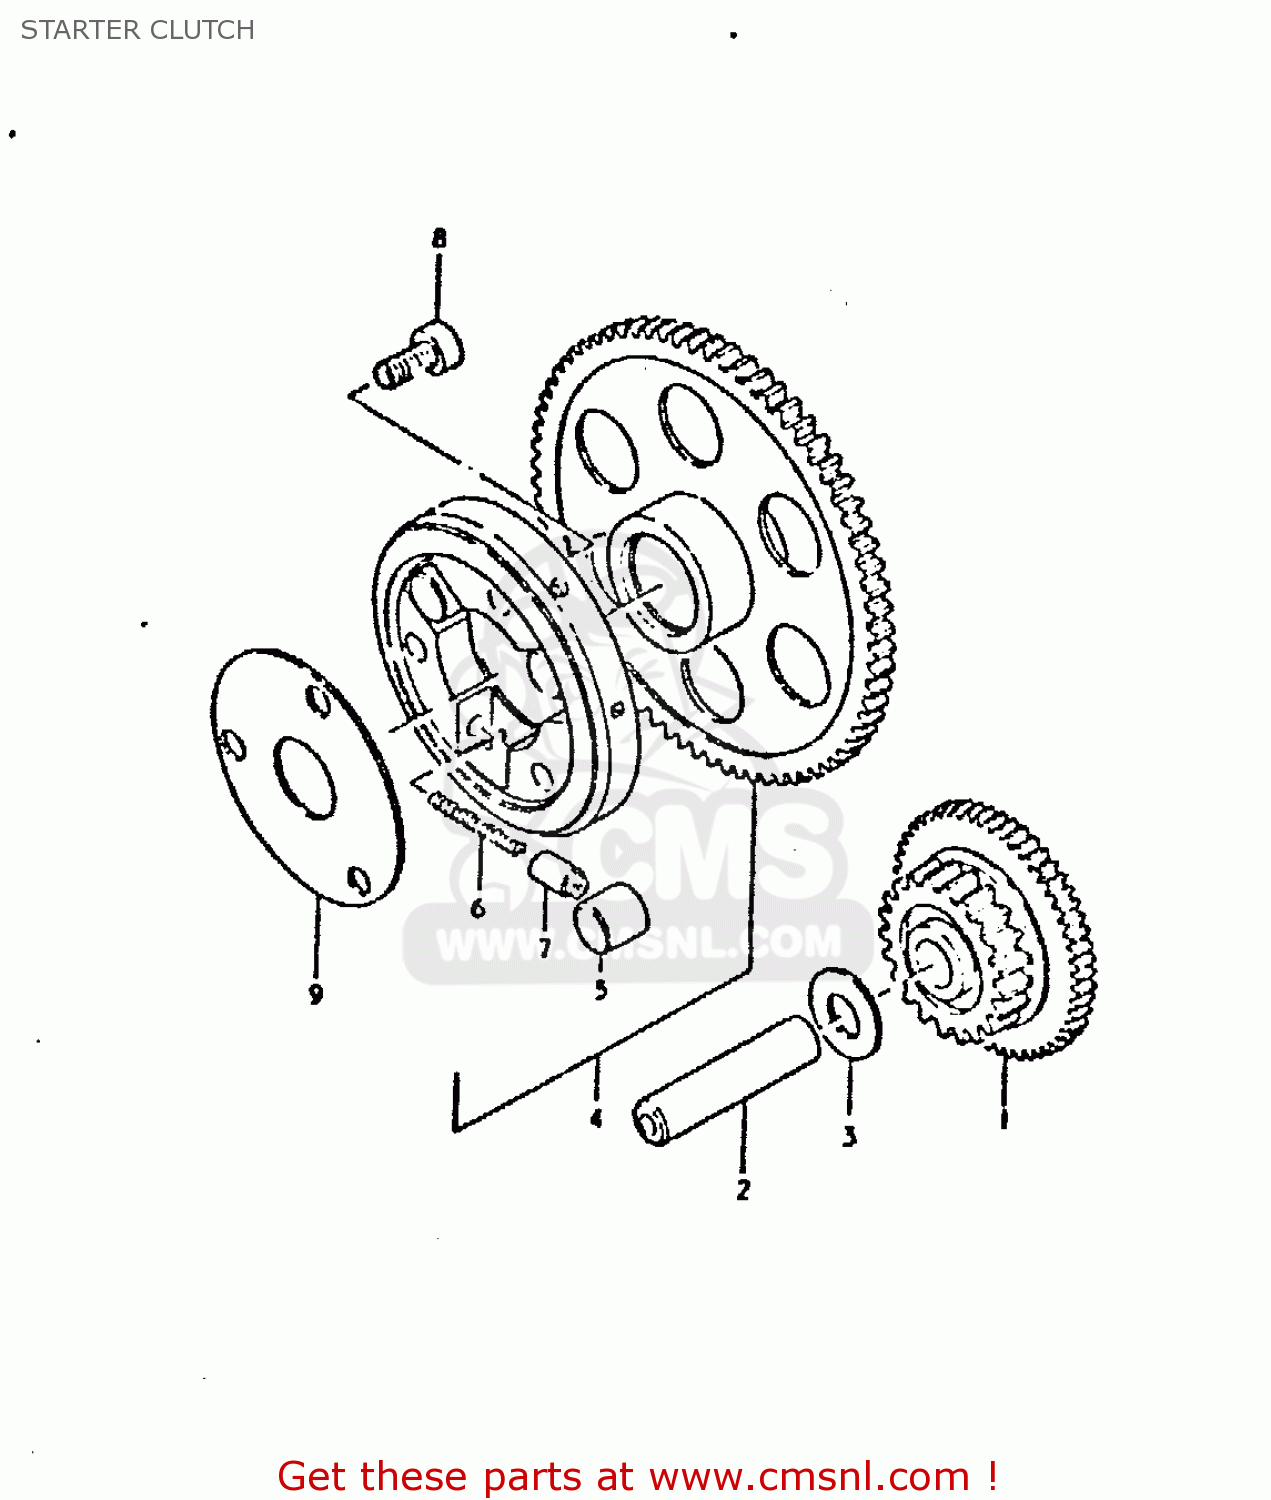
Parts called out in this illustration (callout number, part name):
1	GEAR,STARTER IDLE
2	PIN(7.4X13X56)
3	WASHER
4	CLUTCH SET,STARTER
5	ROLLER(15X13)
6	SPRING
7	PIECE,PUSH
8	BOLT
9	SHIM,STARTER CLUTCH HUB
